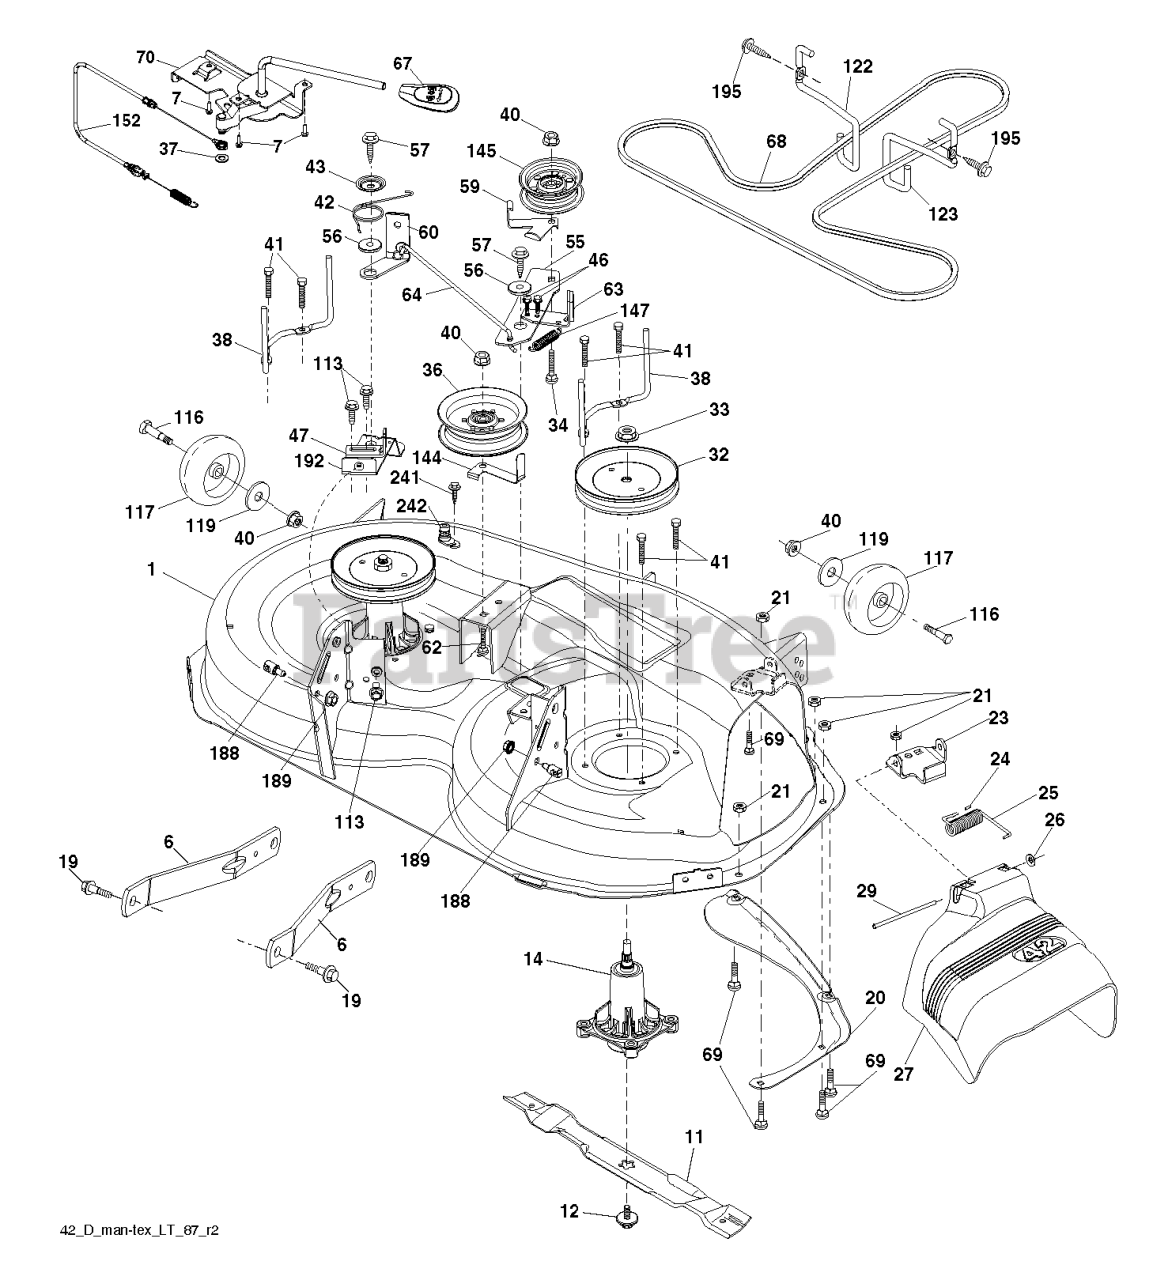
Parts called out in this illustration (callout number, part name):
1	Weldments
6	ARM.SUSPENSION.MOWER.R
11	42" HI-LIFT BLADE
12	SCREW.SEMS.7/16-20X1.HEX.HEAD
14	KIT.MANDREL.NONGREASE.TALL
19	BOLT.SHOULDER
20	BAFFLE.VORTEX
23	BRKT.DEFLECTOR.38"2005+
24	CAP-SLEEVE LT
25	SPRING.TORSION.DEFLECT
26	NUT PUSH M
27	SHIELD.DEFLECTOR.MOWER.42"BLAC
32	PULLEY.MANDREL.5.438.PD
34	GSPW Bolts
36	PULLEY.IDLER.2006
37	WASHER PLAIN WASHER 3/8 X 0.08
38	KEEPER.BLT.PNT.MNDRL.PULL.6.25
40	NUT LOCK FLG 3/8-16 UNC
41	BOLT.HEX.WASHR.HED.313-18X1.19
42	SPRING.TORSION.BRAKE
43	SRPING.TORSION.RETAINE
46	SCREW.1/4-20X5/8
47	BRKT.CLUTCH.CABLE
55	IDLER.ARM.42"
56	SPACER.RETAINER
57	SCREW 3/8-16X1
59	GUARD, BELT
60	ARM BRAKE MOWER
63	ARM BRAKE MOWER
64	LINKAGE.BRAKE.ASM.ZINC
67	HANDLE.CLUTCH.CABLE.LT
70	CLUTCH.ASM.MANUAL.YT.PREDATORQ
113	BOLT.5/16HEX.WHS.HD
117	WHEEL.GAUGE.RALLY.NARROW
122	KEEPER BELT ENGINE LH
123	KEEPER BELT RH
144	KEEPER.BELT.MOWER
145	PULLEY.IDLER.48"PRIMARY
147	RETURN SPRING
152	CABLE.MECHANICAL.CLUTCH
188	STUD.W/"D"ANTI-ROTATION
192	BRKT.BRAKE.STAND.LH.
195	SCREW, 3/8-16X3/4
241	SCREW.TT.#10-32X.5.3/8.FLANGE
242	PORT.WASHOUT
